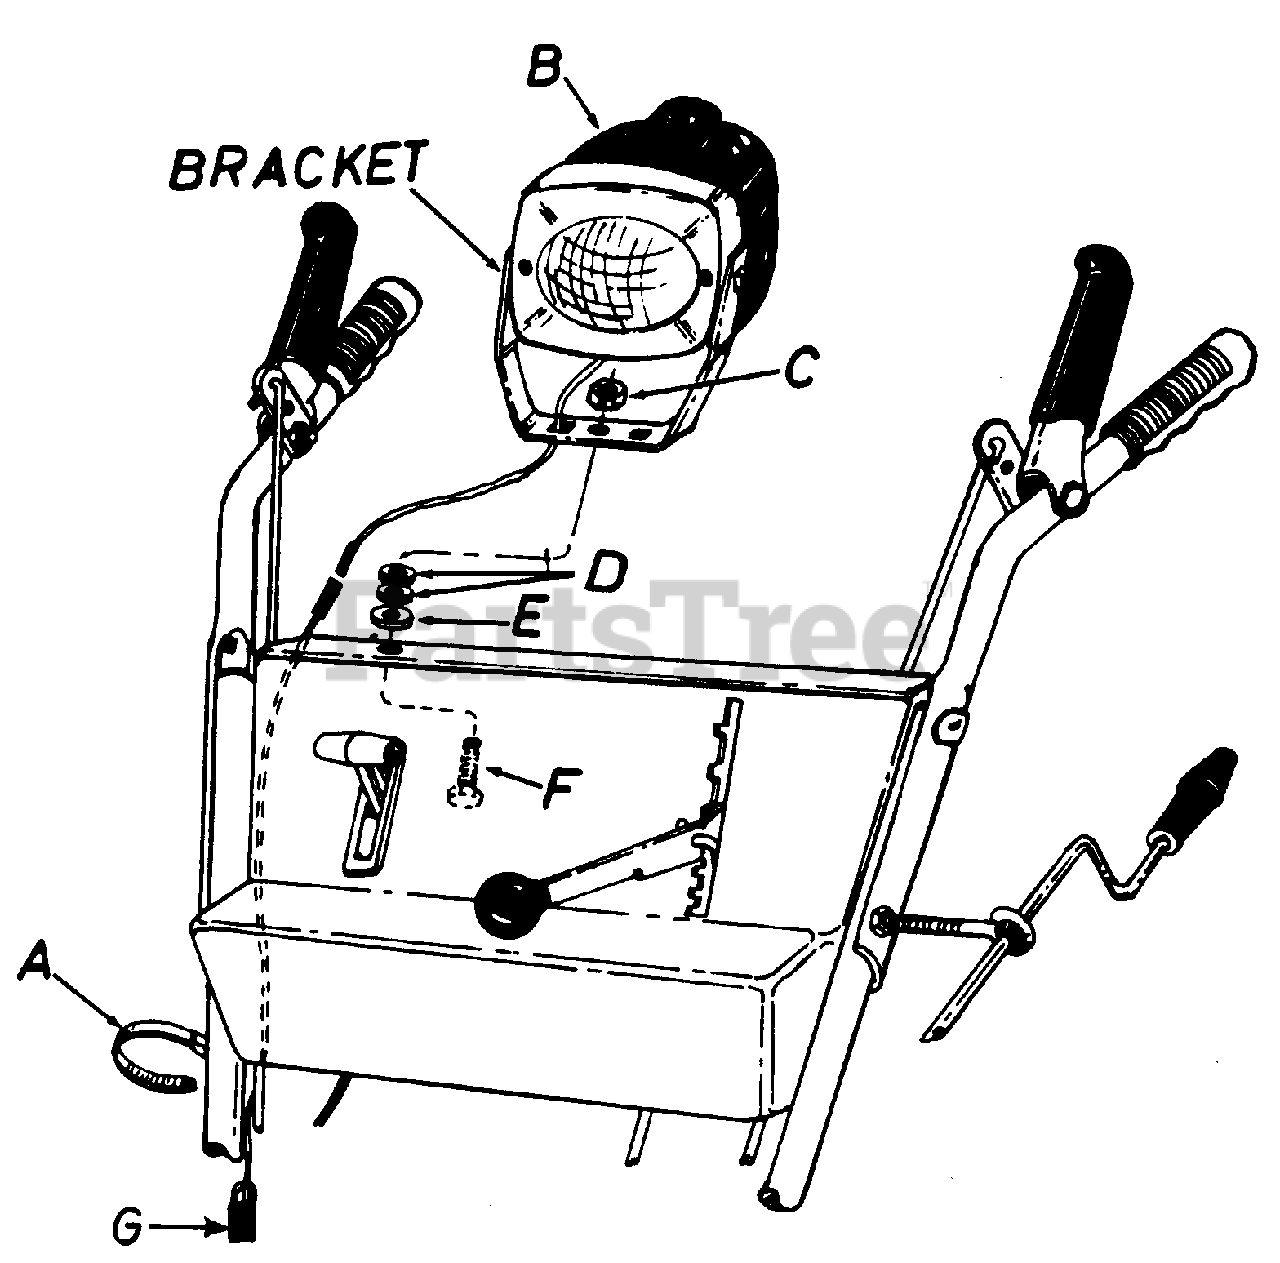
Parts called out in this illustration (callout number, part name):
A	Cable Ties
B	Head Lamp Ass'y. Comp.
C	Hex Cent. L-Nut 5/16-18 Thd.
D	Rubber Wash. .33" I.D. x .87" O.D. x .12 Thk.
E	Flat Wash. .34" I.D. x 1.12" O.D. x .12 Thk.
F	Hex Bolt 5/16-18 x 1.0" 4.
